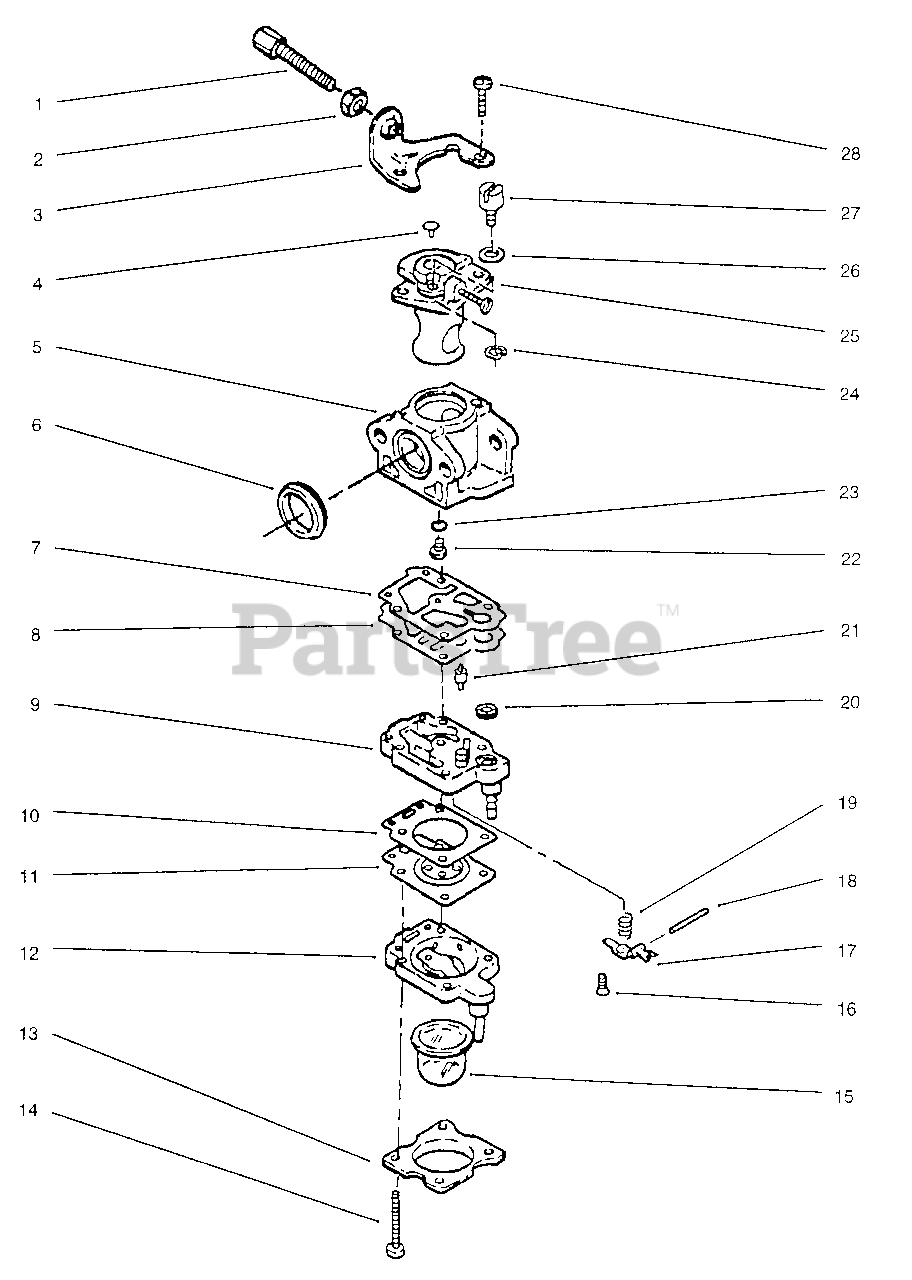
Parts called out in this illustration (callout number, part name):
1	Screw-Cable Adjustment
2	Nut-Lock
3	Bracket-Throttle
5	Body-Carburetor (Ref.)
7	Gasket-Diaphragm
8	Diaphragm
9	Body Ass'y-Fuel Pump (Incl. Ref. #20)
10	Gasket-Diaphragm
11	Diaphragm
12	Body-Primer
13	Cover-Primer
15	Bulb-Primer
21	Valve-Needle
22	Jet- #43
23	"O"Ring-Main Jet
24	Ring-Clip
25	Valve-Throttle
27	Swivel-Cable
